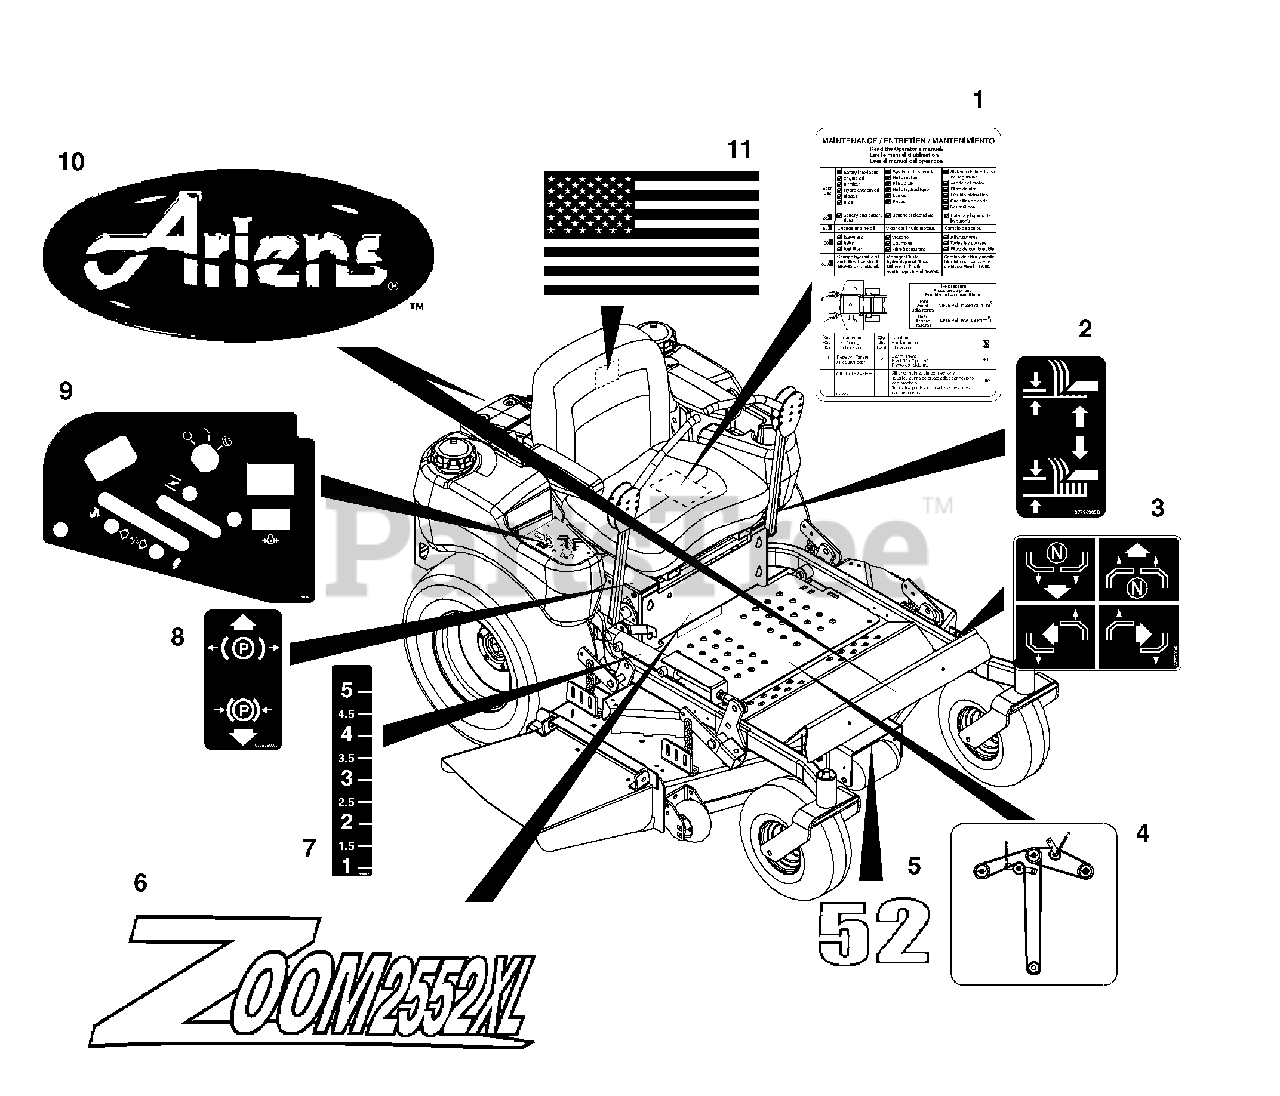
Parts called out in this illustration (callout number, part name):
1	DECAL, MAINTENANCE INSTRUCTION
2	DECAL- LIFT LEVER
3	DECAL, INSTRUCTIONAL-STEERING
4	DECAL, GRAVELY BELT DIAGRAM
5	DECAL - 52"
6	DECAL, ZOOM 2552 XL
7	DECAL, HEIGHT OF CUT
8	DECAL, PARKING BRAKE LEVER
9	DECAL CONTROL PANEL
10	DECAL, ARIENS JEWEL
11	DECAL, AMERICAN FLAG
